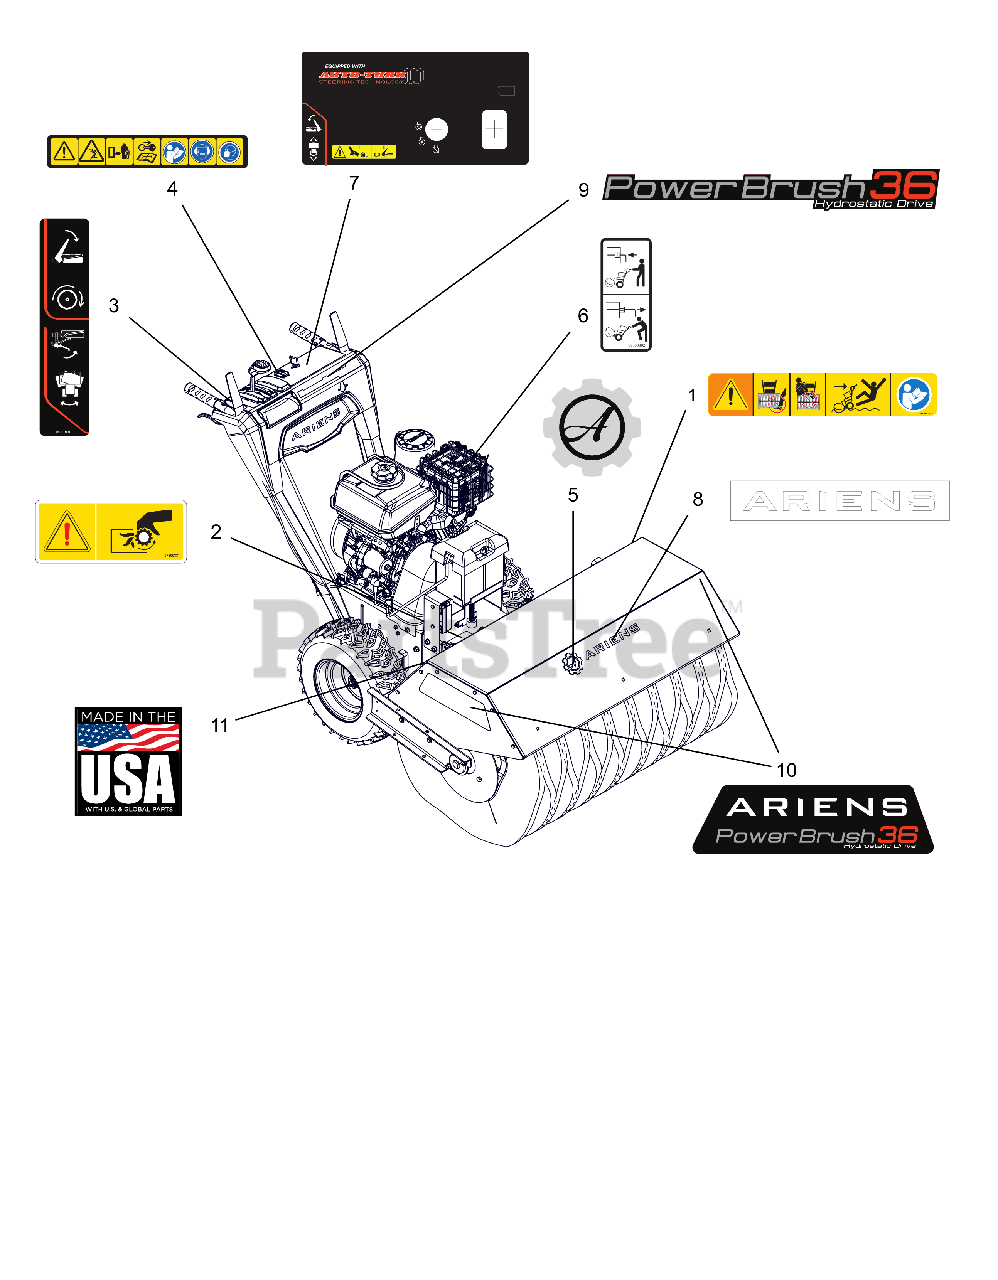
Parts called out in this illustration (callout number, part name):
1	DECAL, DANGER -POWER BRUSH-CE
2	DECAL, PTO WARNING
3	DECAL,CONTROL,BRUSH,RH
4	DECAL, SAFETY, DASH, BRUSH
5	DECAL, ARIENS-GEAR BADGE -THK
6	DECAL, HYDRO BRUSH BYPASS
7	DECAL,CONTROL-12V HYDRO BRUSH
8	DECAL - ARIENS 9.625"
9	DECAL, DASH - PB 36 HYDRO
10	DECAL - ARIENS PB 36 HYDRO
11	DECAL, MADE IN USA
